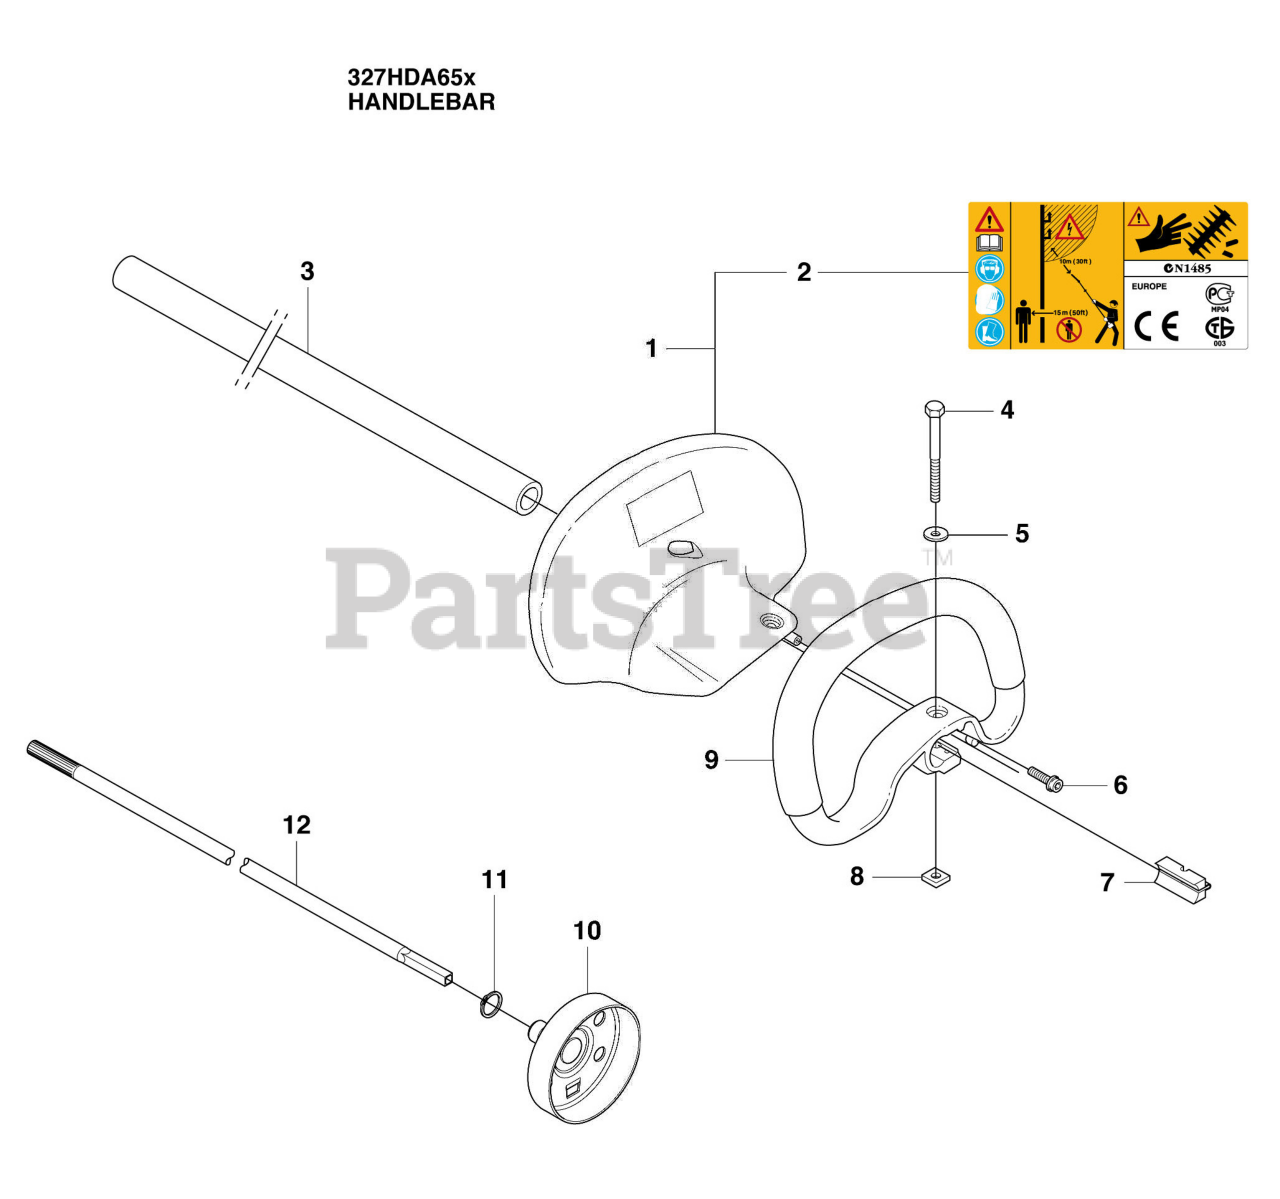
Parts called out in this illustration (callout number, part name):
1	RP HAND GUARD
2	Warning Label
5	Washer, M6
7	Spacer, Plastic
9	Handle
10	Clutch Drum
12	DRIVE AXLE HDA55
